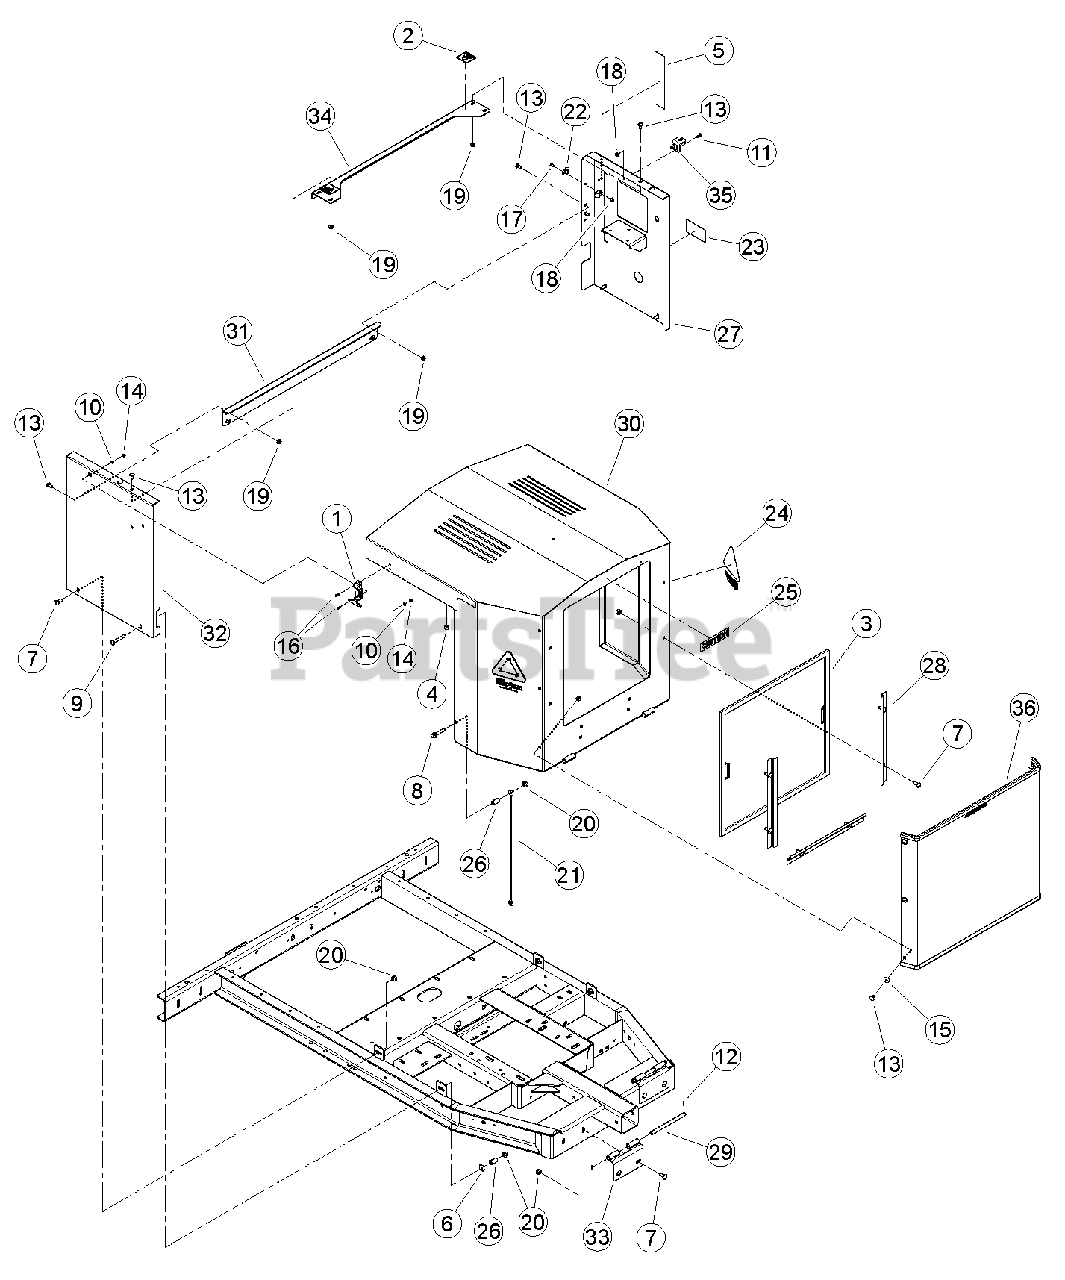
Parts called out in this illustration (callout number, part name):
1	LATCH, FLEXIBLE DRAW
2	DECAL, SHIELD DANGER ISO
3	SCREEN, RADIATOR INLET
4	BUMPER, RUBBER
5	DECAL, CHIPPER ENGAGEMENT
6	WASHER, 3/8" FLAT ZP
7	BOLT, 3/8 X 1" GR5 CRG NC ZP
8	BOLT, 3/8 X 2 FLANGE NC
9	BOLT, 3/8 X 2-1/2" GR5 CRG NC ZP
10	WASHER, 3/16" FLAT ZP
11	BOLT, 1/4 X 3/4 GR5 CRG ZP
12	ROLL PIN, 5/32 X 3/4" PLAIN
13	BOLT, 5/16 X 3/4 GR5 CRG NC ZP
14	NUT, 10/24 NYLOCK TYPE NM ZP
15	WASHER, 5/16" ID 7/8" OD NYLON FLAT
16	SCREW, MCH 10-24 X 1/2" PAN HD PH ZP
17	RIVET, AL BLIND 1/4 X 3/4 DOME HEAD
18	NUT, 1/4-20 NYLOCK-FLANGE
19	NUT, 5/16-18 NYLOCK-FLANGE
20	NUT, 3/8-16 NYLOCK FLANGE
21	LANYARD, STEEL W/ PVC 1/8 X 20"
22	CLAMP, CABLE MOUNT
23	DECAL, FEED SPEED
24	DECAL, CHIP IT
25	DECAL, MODEL CH611DH
26	IDLER SPACER
27	WELDMENT, ENGINE RIGHT
28	BRACKET, SCREEN HOLDER
29	PIN, HOOD HINGE PLATED
30	WELDMENT, 6 INCH HOOD
31	PLATE, HOOD SUPPORT
32	SHIELD, ENGINE LEFT
33	WELDMENT, HOOD HINGE
34	BRACE, ENGINE SHIELD
35	BASE, HOOD LOCK
36	ASSEMBLY, 6 INCH SCREEN
